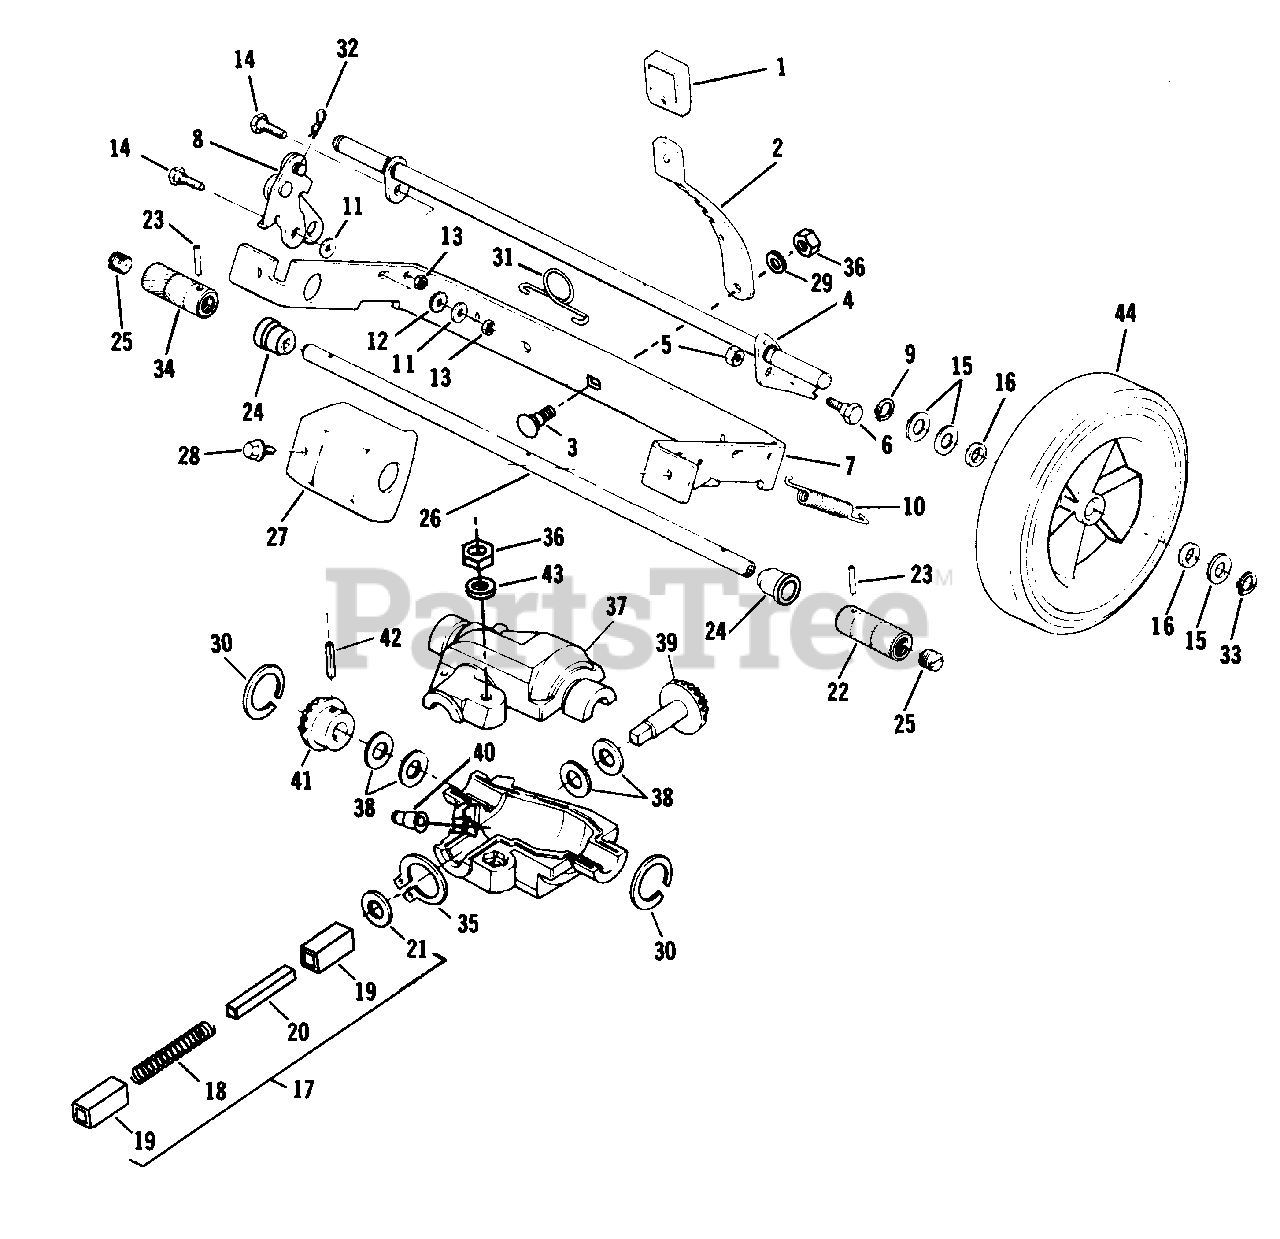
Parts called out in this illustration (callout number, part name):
1	Knob-Rear Height Adj. Lvr.
2	Lever-Rear Height Adj.
3	Shoulder Bolt-Ht. Adj. Lever
4	Axle Assembly
5	Locknut
6	Bolt-Shoulder
7	Bracket-21" Axle
8	Clutch Assembly
9	Retaining Ring
10	Spring
11	Washer
12	Lockwasher
13	Stopnut
14	Bolt-Shoulder
15	Washer
16	Washer-Felt
17	Driveshaft Assembly
18	Spring-Compression
19	Bushing-Driveshaft
20	Driveshaft
21	Washer
22	Drive Roller-L.H.
23	Pin-Spiral
23	Pin-Groove
24	Sleeve and Bearing Assembly
25	Plug
26	Shaft
27	Guard-Roller
28	Screw
29	Washer
30	Ring-Retaining
31	Spring-Height Adjust
32	Lock Pin
33	Retaining Ring
34	Drive Roller-R.H.
35	Ring-Retaining
36	Locknut
37	Gear Box Assembly
38	Washer
39	Gear-Drive
40	Zerk Fitting
41	Gear Driven
42	Spring Pin
43	Washer
44	Wheel-Rear
